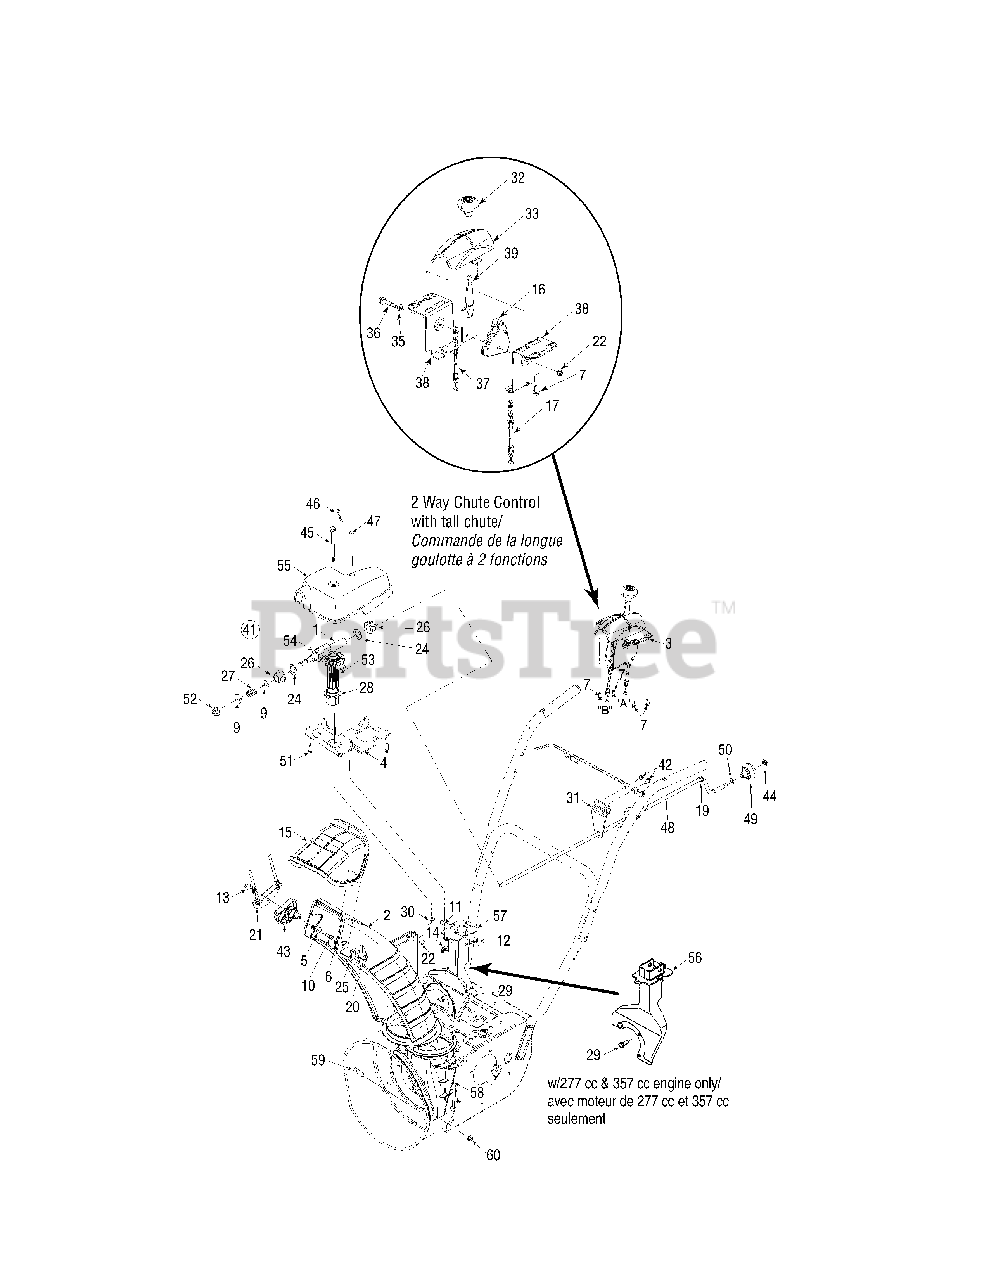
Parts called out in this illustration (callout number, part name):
1	Hex Shaft
2	Tall Lower Chute
3	2 Way Chute control Assembly
4	Chute Gear Rotation Bracket
5	Carriage Bolt 5/16-18 x 1.50 Gr. 2
6	Carriage Screw 5/16-18 x 1.0
7	Hi-Lo Screw 1/4-15 x .5
9	Flat Washer .38 x .92 x .110
10	Hex Tapp Scr 1/4 x .75" Lg.
11	Clevis Pin 3/8 x 1.87
12	Bow Tie Cotter Pin
13	Flange Locknut 5/16-18 Gr. F Nylon
14	Wing Nut 1/4-20
15	Upper Chute w/Export Label, Remote
16	Cable Guide
17	Cable
20	Handle Knob Assembly
22	Hex L-Flanged Nut 1/4-20 Gr. F Nylon
24	Flat Washer .625 x 1.0 x .067
25	Flat Washer .349 ID x .879 OD x .063
26	Hex Flg. Bearing
27	Compression Spring .39 x .60 x .88
28	Hex Bearing
29	Hex Hd. Cap Screw 5/16-24 x .75
30	Flat Washer .25 ID x .63 OD x .0515 HT.
33	control Cover - 2 Way
35	Spring Washer .390 x .625 x .012
36	Flg Shlder Screw .310 x .995: 1/4-20
37	Cable - w/standard chute
37	Cable - w/tall chute
41	Gear box Assembly
42	Hex Wash Hd TT Screw 1/4-20 x .625
43	Cable Guide
44	Push Nut 3/8" Rod
45	Flg. Shoulder Screw .312 x 3.5: 1/4-20
46	Internal Cotter Pin
47	Hex. Hd. Cap Screw 1/4-20 x 3.0 Gr. 5
48	Chute Crank .375 Dia. x 30.5" Lg.
50	Flat Washer .375 x .738 x .063
51	Hi-Lo Screw #12-16 x .75
52	Hex L-Flanged Nut 3/8-16 Gr. F Nylon
53	Gear 14 teeth helical w/hub
54	Worm - Nylon
55	Cover
56	Chute Sup. Bkt. Ass'y
57	Chute Support Bracket Ass'y
58	Chute Adapter
59	Carriage Screw 1/4-20 x .75 Gr. 5
60	Hex L-Flanged Nut 1/4-20 Gr. F Nylon
